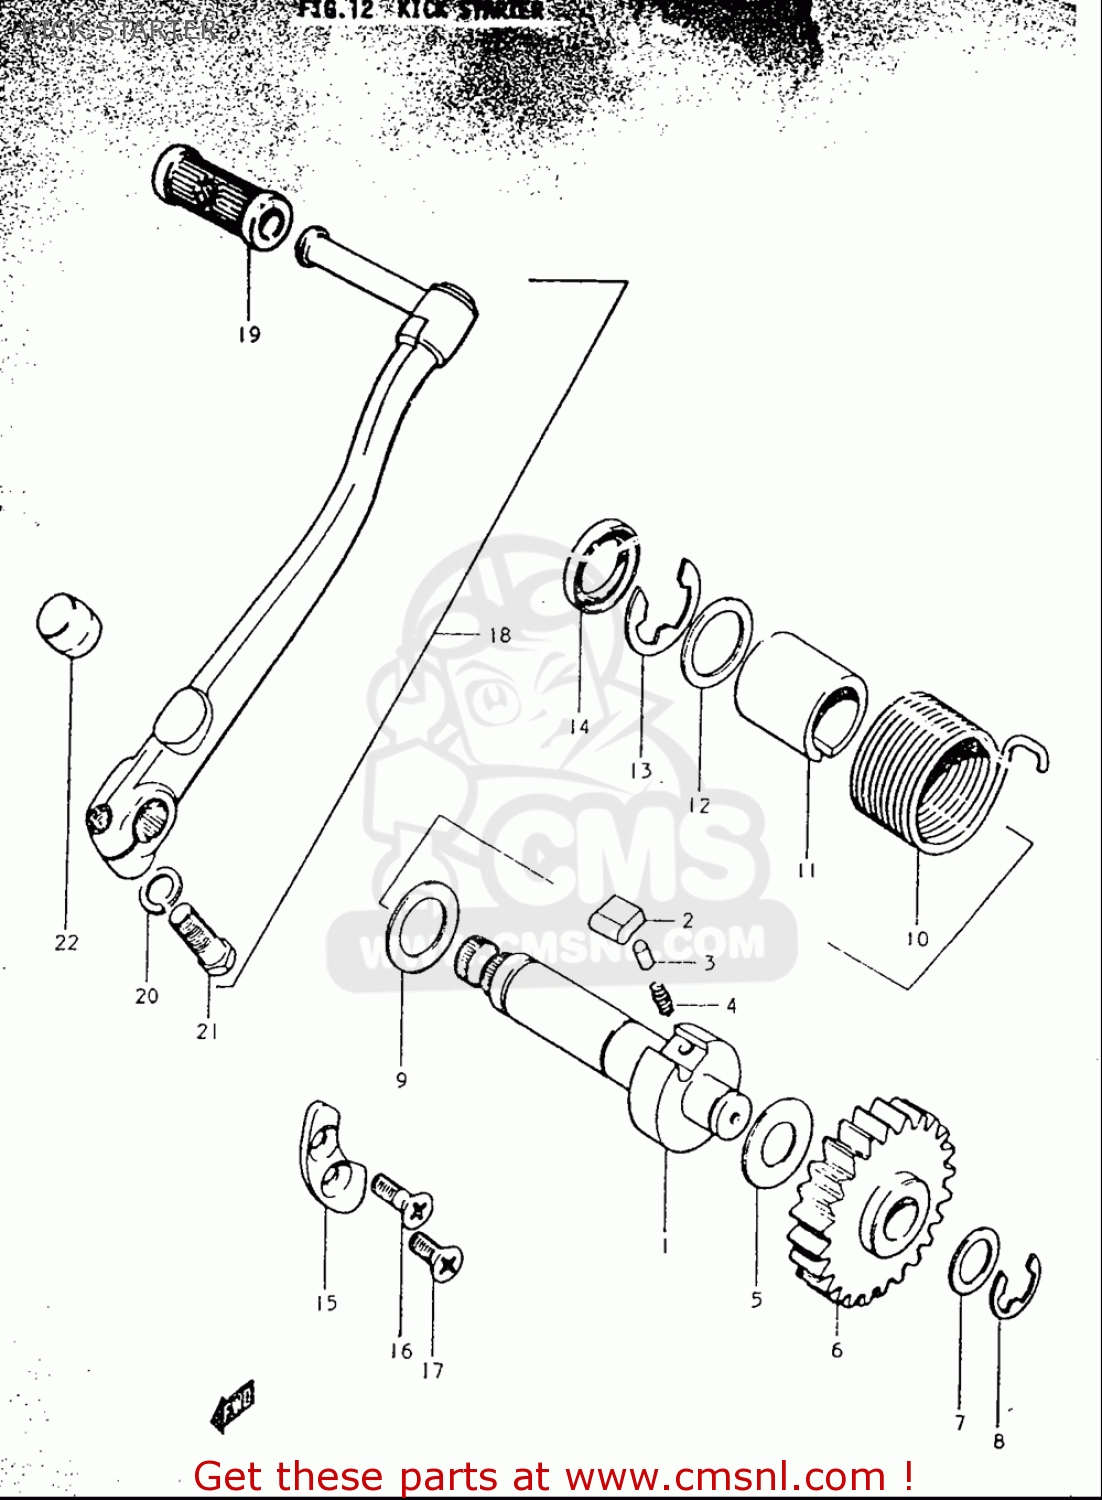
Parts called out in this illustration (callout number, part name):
3	PIN(5X15.5)
5	WASHER(16X30X1)
8	E RING
9	WASHER
10	SPRING
12	WASHER
16	SCREW
17	SCREW(6X19)
19	RUBBER,KICK STARTER PEDAL
20	WASHER,LOCK
21	BOLT
